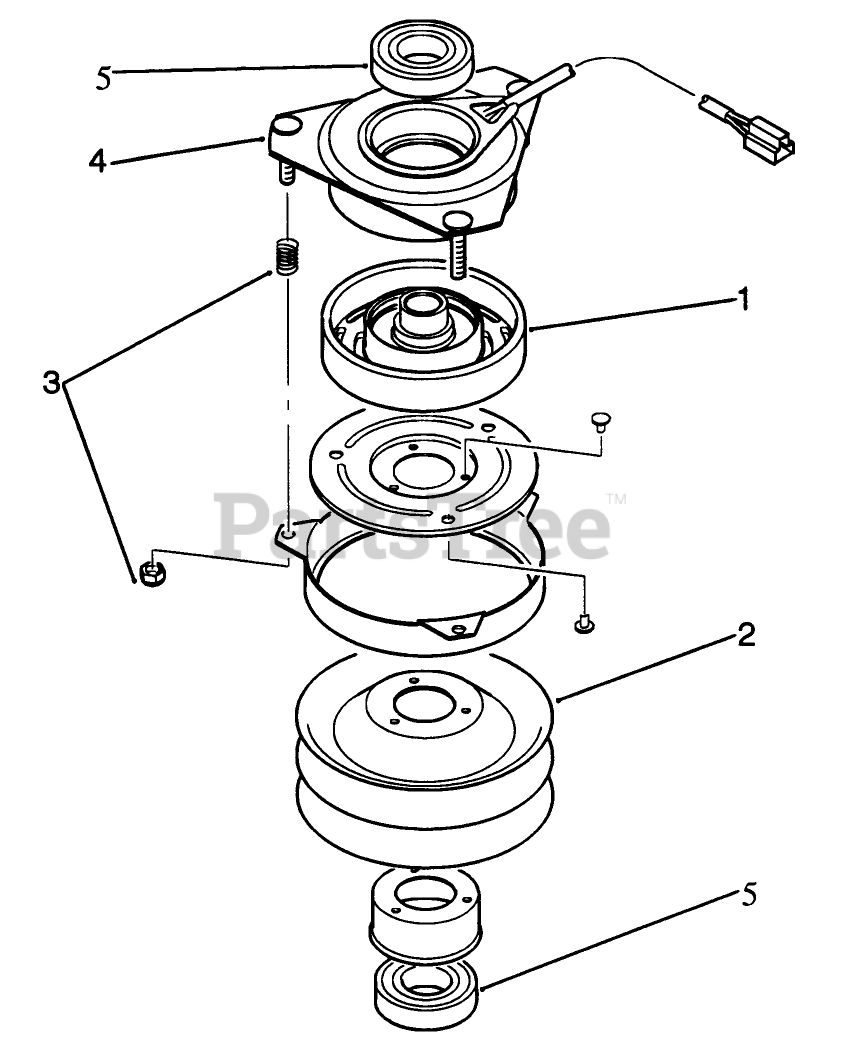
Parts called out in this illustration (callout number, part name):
1	Assembly-Rotor
2	Assembly-Armature
3	Accessories-Nuts Springs
4	Assembly-Field
